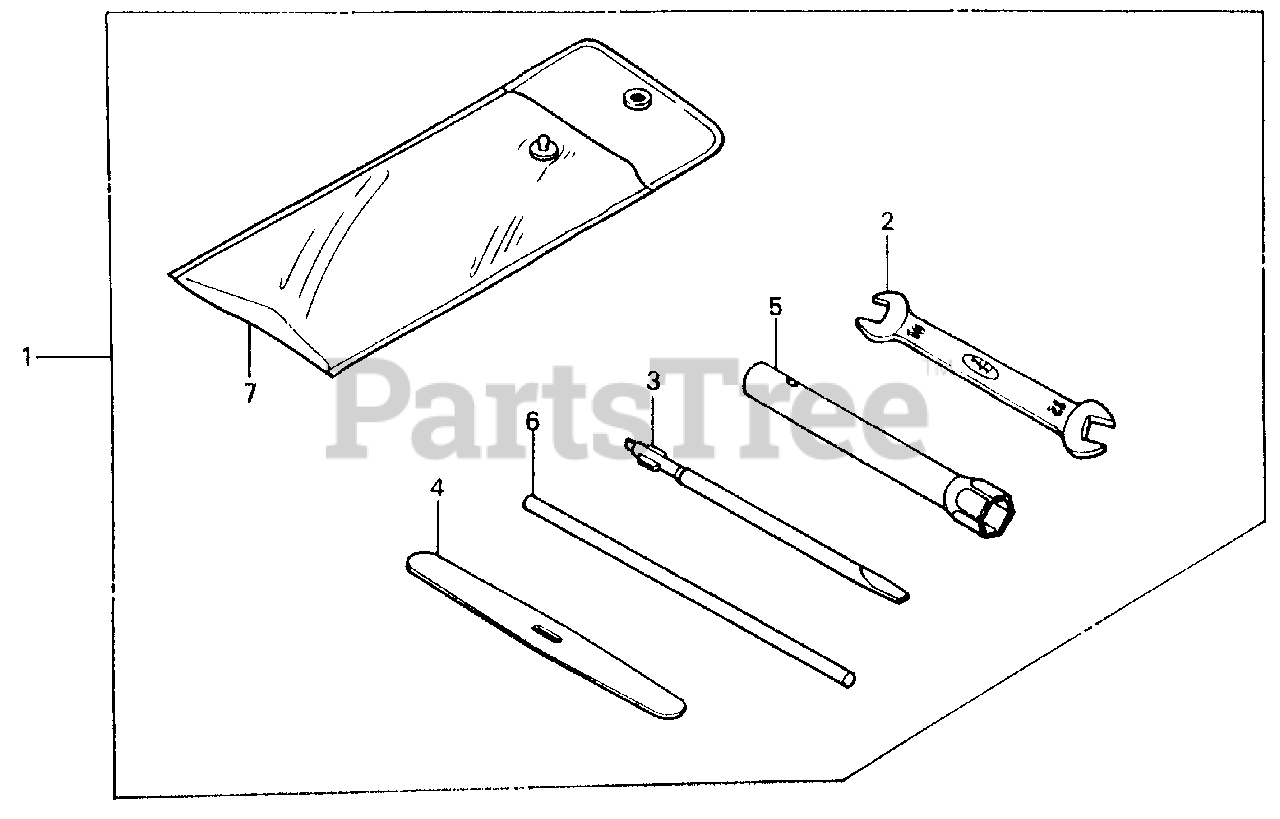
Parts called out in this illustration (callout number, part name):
2	WRENCH (10X12) (OPEN END)
3	SCREWDRIVER 3, STRAIGHT SLOT (NO.2)
4	LEVER, TIRE
5	WRENCH, BOX (P21)
6	BAR A, HANDLE
